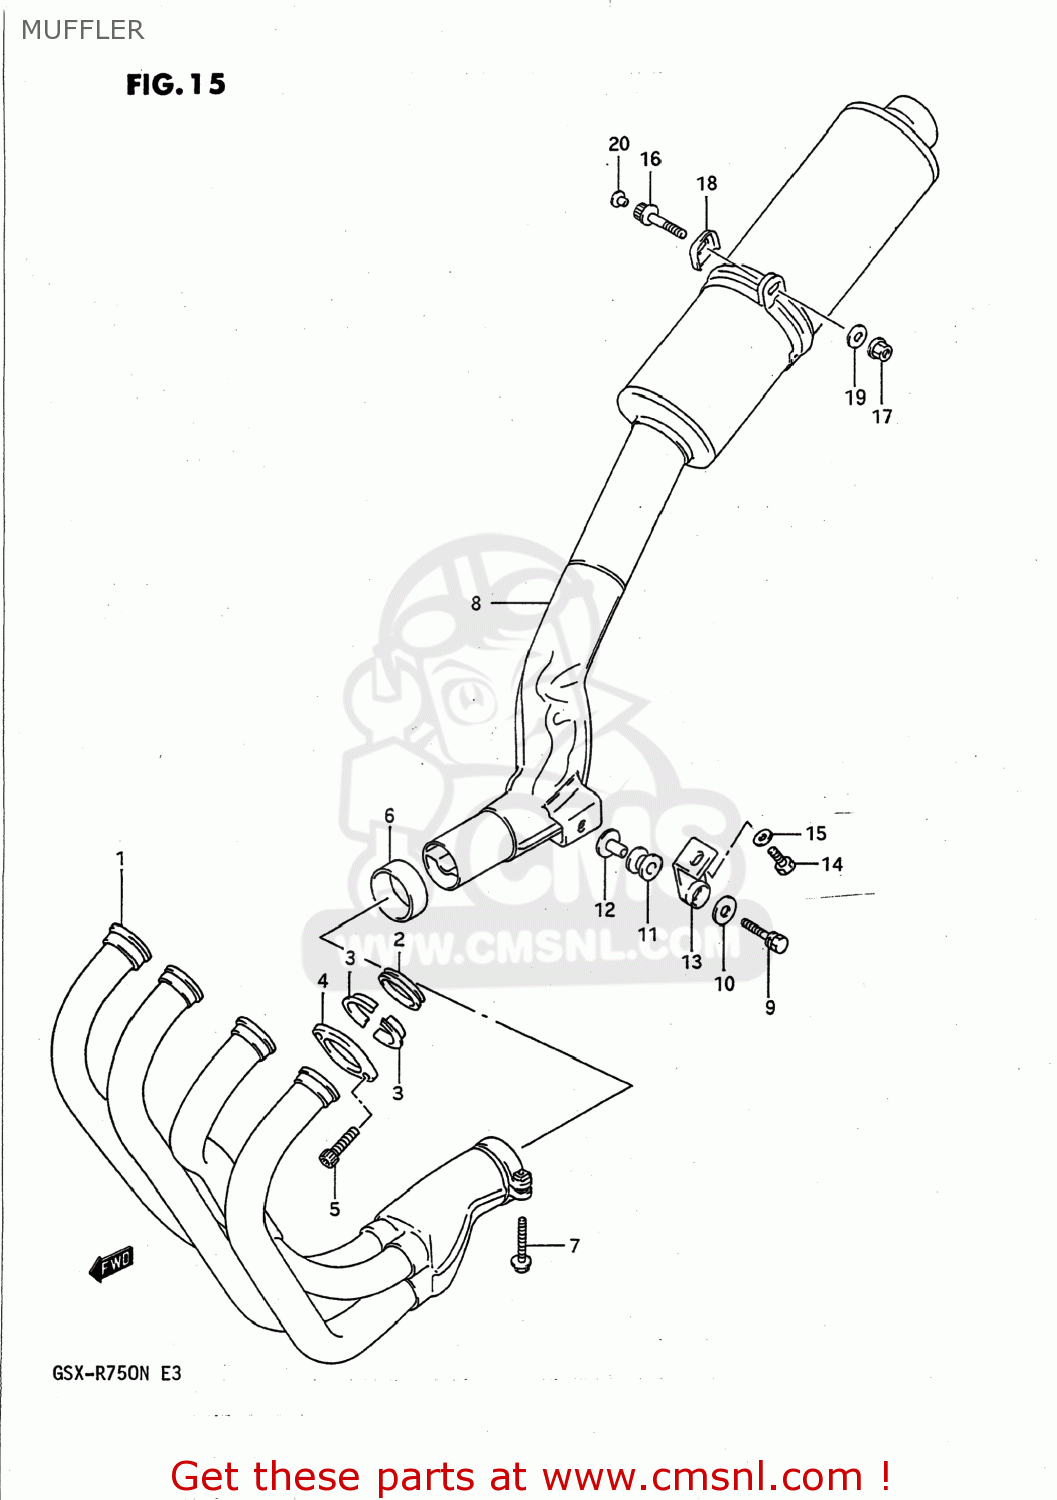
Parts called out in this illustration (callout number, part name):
1	EXHAUST ASSY
2	GASKET,EXHAUST (NAS)
3	PLATE,EXHAUST PIPE
4	CLAMP,EXHAUST PIPE
5	BOLT
6	CONNECTOR,MUFFLER
7	BOLT 8X45
8	MUFFLER ASSEMBLY
9	BOLT 8X35
10	WASHER
11	CUSHION
12	SPACER(8.6X12X18.5)
13	DAMPER COMP,MUFFLER SUPPORT F
14	BOLT(8X20)
15	WASHER
16	BOLT
17	NUT
18	WASHER,MUFFLER SUPPORT
19	WASHER (10.5X24X2.3)
20	CAP(OD:12)
